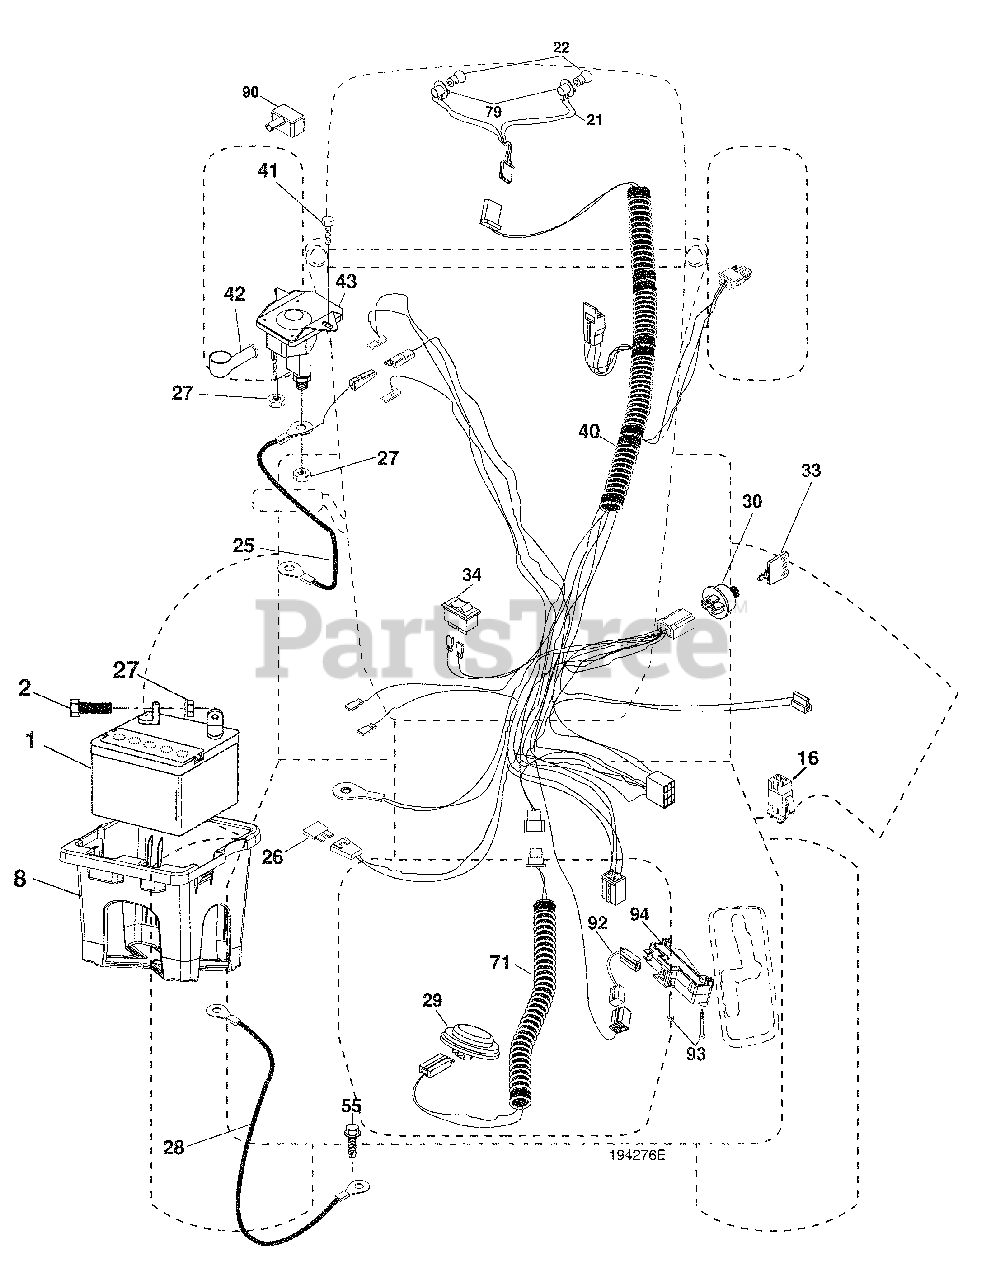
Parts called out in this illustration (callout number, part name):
1	Battery
2	Bolt Hex Head 1/4-20 x 3/4
8	Box Battery
16	Switch Interlock Push-In
21	Harness Socket Light W/4152J
22	Bulb Light
25	Cable Starter
27	Nut Keps Hex 1/4-20 unc
28	Cable, Ground
29	Switch, Seat
30	Switch, Ign
33	Key, Ignition
34	Switch Light / Reset
40	Harness Ign. Dash
41	Screw Thd Cut 1/4-20 x 1/2
42	Cover, Terminal
43	Solenoid
55	Screw Thdrol 5/16-18 x 1/2 TYTT
71	Harness Ign.
79	Socket Asm. Bulb Twistlock
90	Cover Terminal
92	Harness Pigtail Reverse Switch
93	Screw Plastite 10-14 x 2.0
94	Module Reverse ROS
